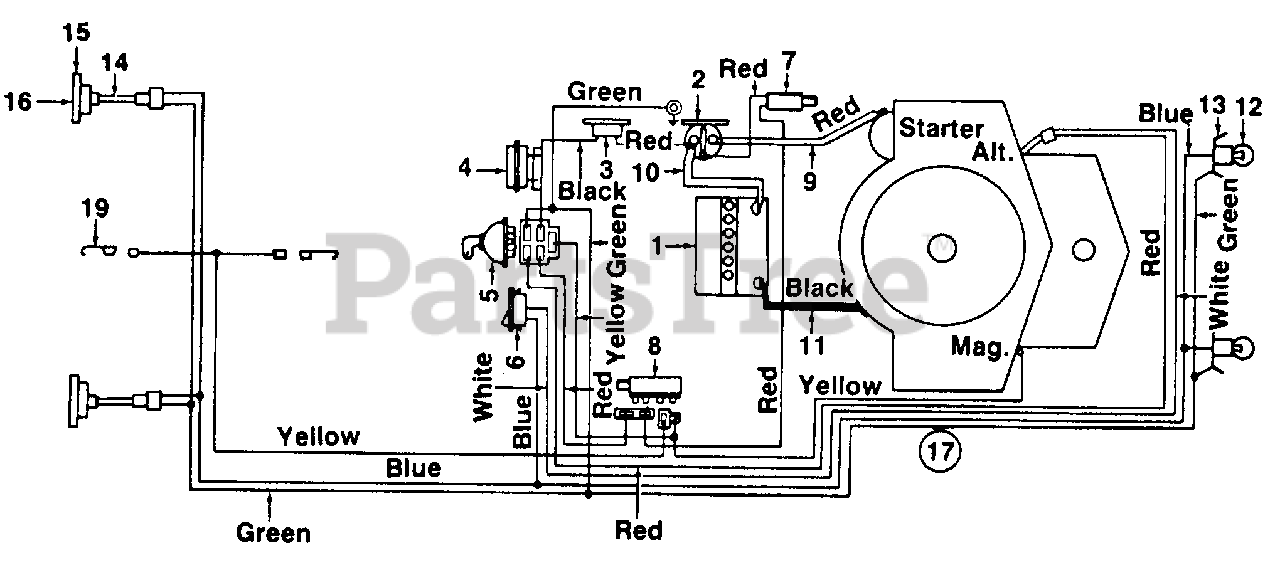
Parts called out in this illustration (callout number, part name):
1	Battery
2	Solenoid
3	Circuit Breaker
4	Ammeter
5	Ignition Switch
6	Light Switch
7	Safety Switch
8	Safety Switch
9	Electric Wire 14" Lg.
10	Electric Wire 7.5" Lg.
11	Ground Wire 7.5" Lg.
12	Lamp
13	Socket
14	Taillight Harness
15	Taillight Ass'y.
16	Taillight Bulb
17	Wire Harness
19	Spring Switch
